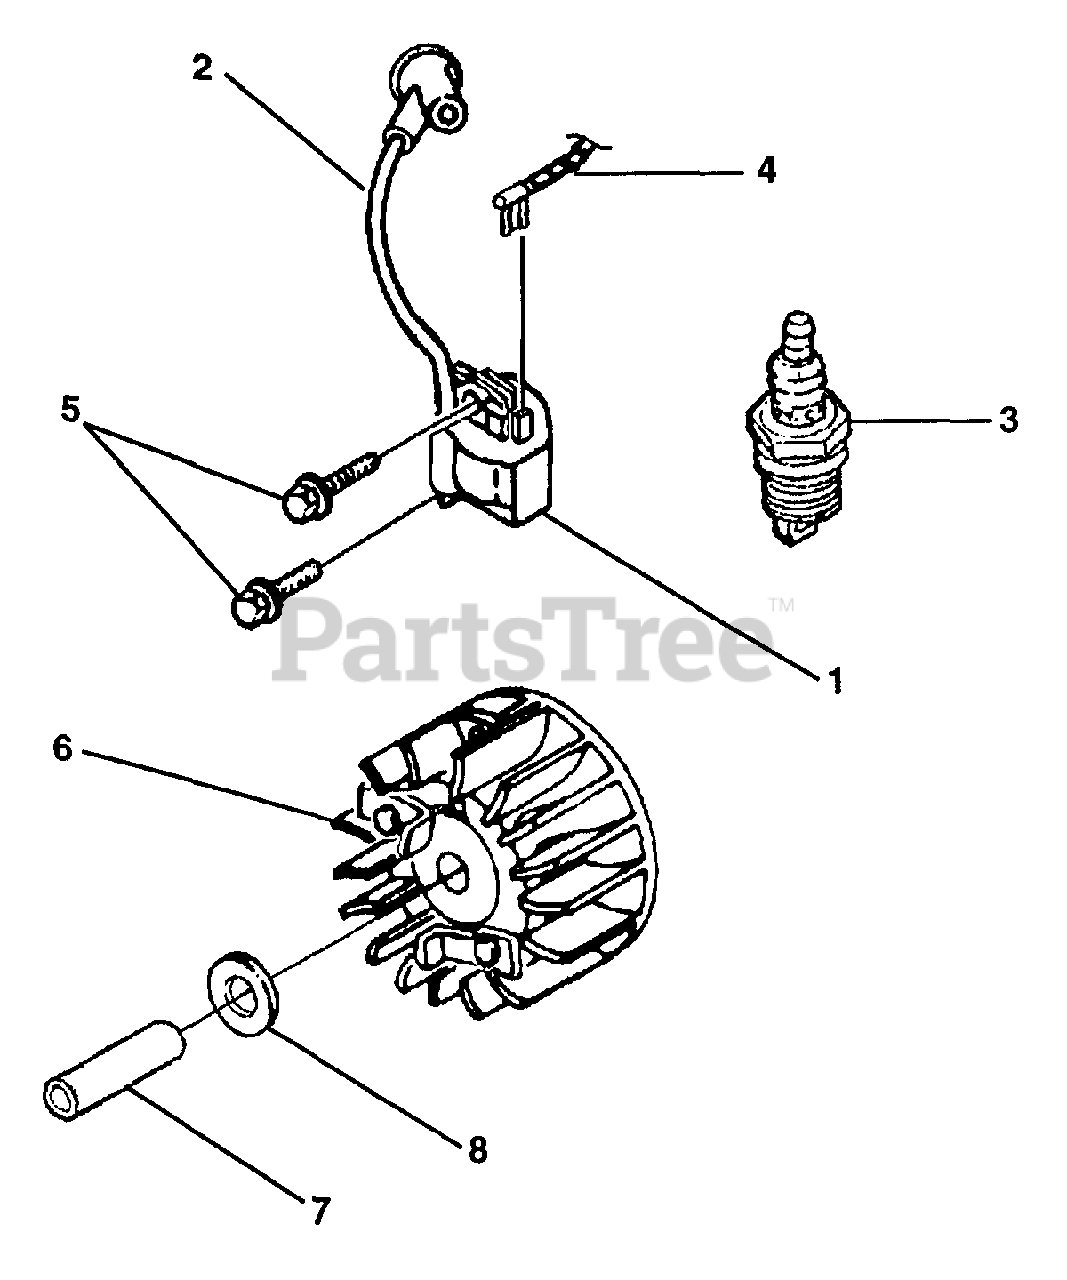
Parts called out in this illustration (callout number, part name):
1	IGNITION MODULE
2	TERMINAL, BOOT
3	SPARK PLUG (DJ-7Y)
4	LEAD WIRE W/TERM.
5	SCREW 8-32 X 1"
6	ROTOR
7	SPACER, FAN
8	WASHER, FLAT
